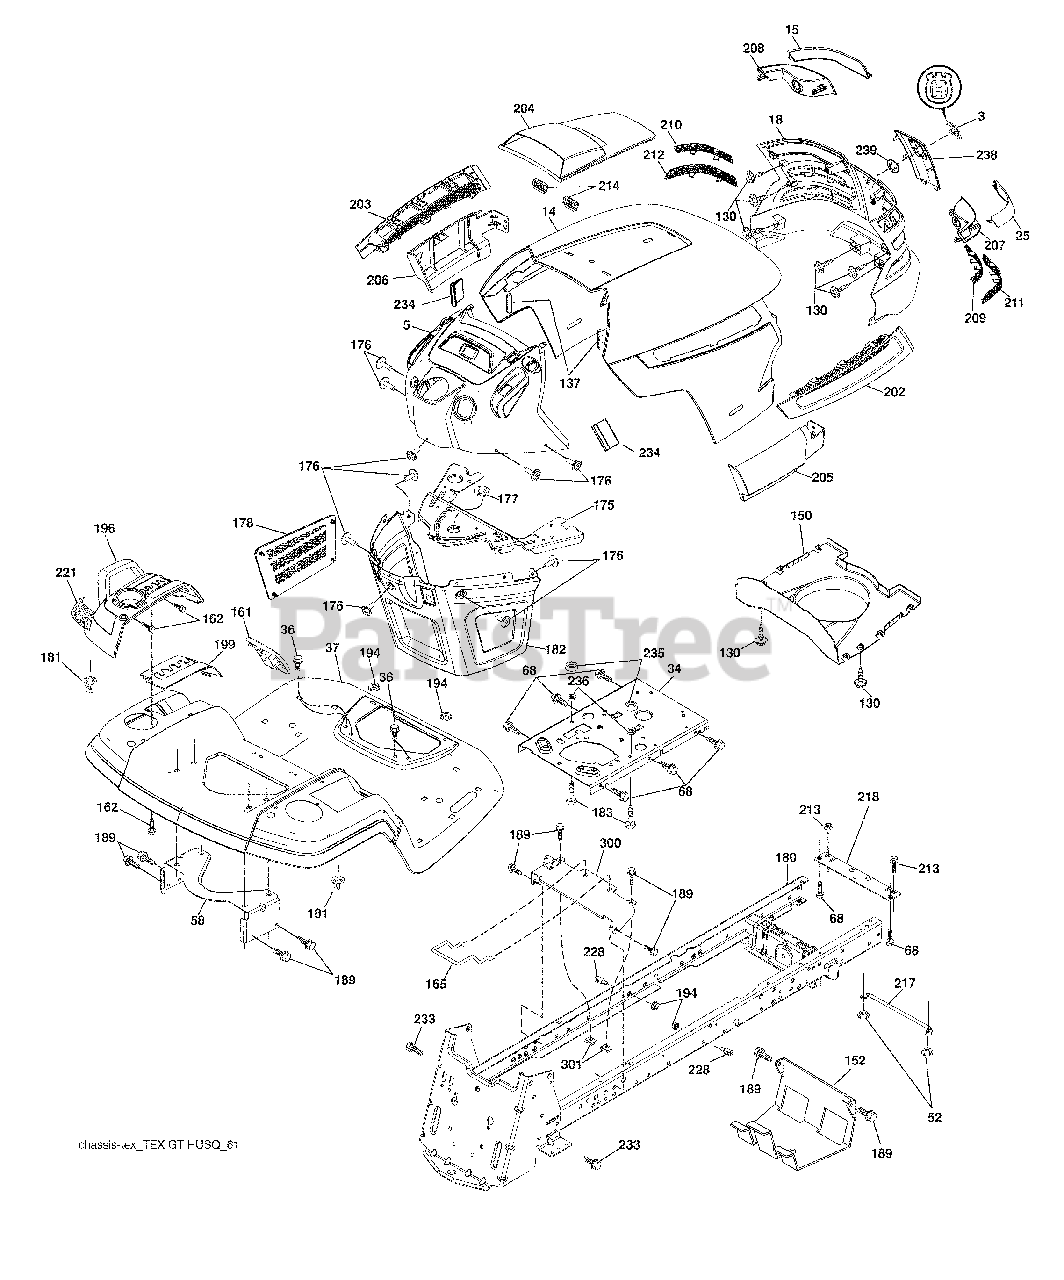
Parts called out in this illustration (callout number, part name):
3	Logo Husq.
5	Dash
14	Hood
34	Plate Engine
36	Screw 5/16-18 x 3/4
37	Fender
52	Nut Crown Lock 5/16-18
58	Bracket Fender
68	Screw 5/16-18 x 1/2
130	Screw #10 x 0.750 BOS Thread
137	Bumper Dash
150	Duct Heat Hood
152	Shield Browning/Debris
161	Console Fuel Window
162	Screw Hex Wsh Hi-Lo 1/4 x 1/2
165	Bracket Support Tank
175	Crossmember
176	Screw 10-24 x 5/8 Wshd Qdrx
177	Bushing Steering
178	Cargo Asm. Net
180	Chassis
181	Bushing Mtg. Fender Crgo.
182	Dash Lower
183	Bolt Fin Hex 5/16-18 unc x 1-1/4
189	Screw 5/16-18 x 3/4
194	Nut Lock Hex Flange 5/16-18
196	Console Asm. Deck Lift
199	Plate Deck Lift
202	Vent Side Hood RH
203	Vent Side Hood LH
204	Vent Asm Hood Top
205	Skirt Hood Side RH
206	Skirt Hood Side LH
209	Insert Hex Top RH
210	Insert Hex Top LH
211	Insert Hex Bottom RH
212	Insert Hex Bottom LH
213	Bolt Hex HD 5/16-18 unc x 3/4
214	Clip Retainer
221	Reflector LH
228	Stud Fastener
233	Bolt Shoulder
234	Bumper Hood
235	Spacer Fender
236	Nut Center Lock 5/16-18 unc
238	Trim Husq.
300	Strap Asm Cross
301	Nut Speed 5/16-18
